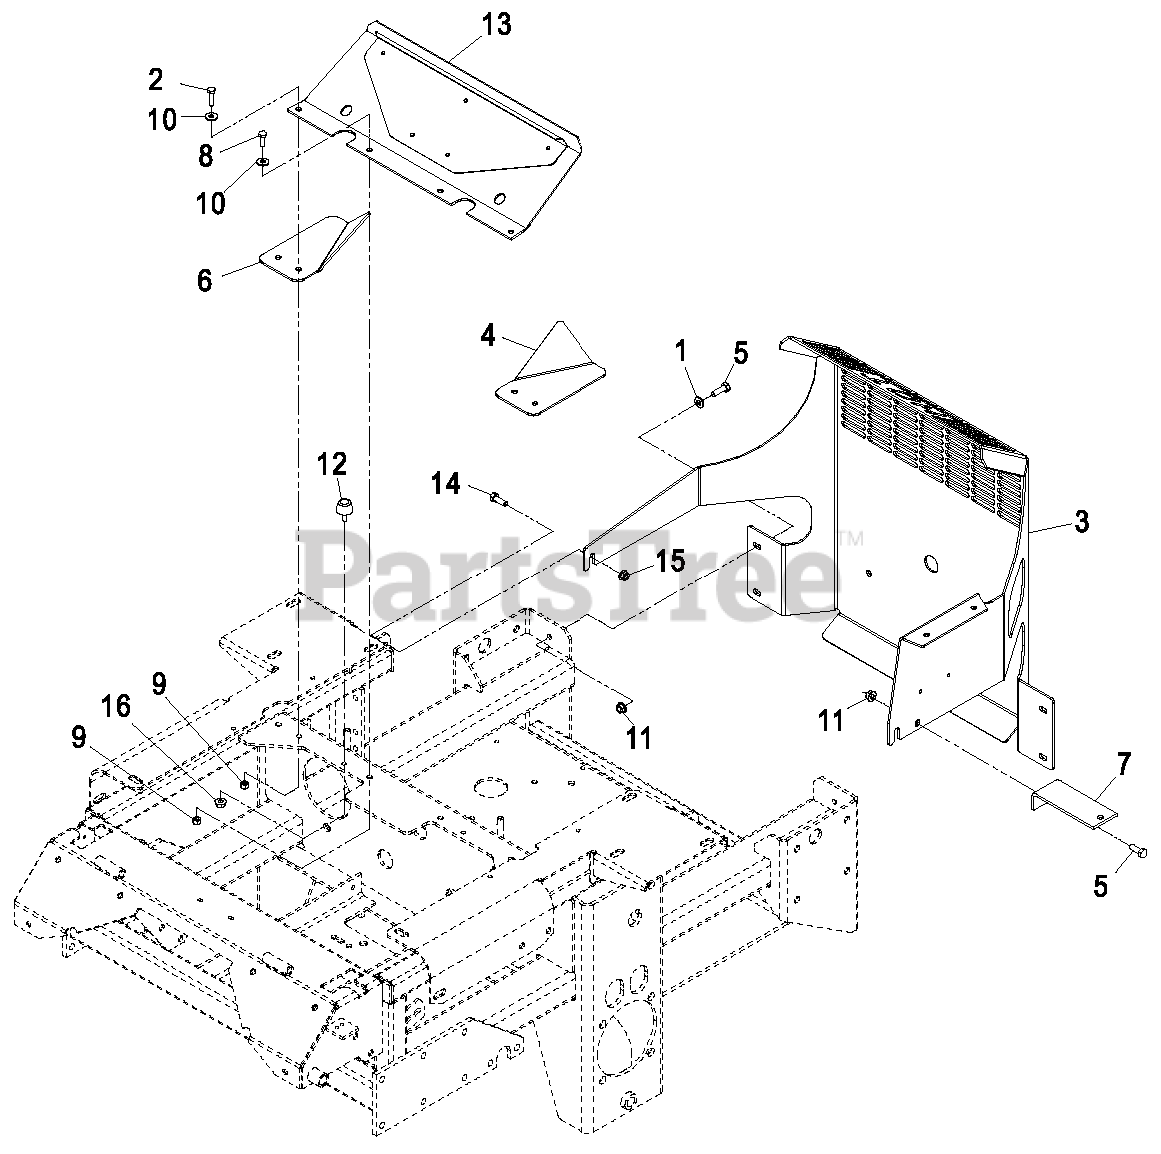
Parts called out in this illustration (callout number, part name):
1	WASHER-PLAIN
2	SCREW-HH
3	GUARD,REAR-LXS AC
4	SUPPORT-FRONT COVER, LH
5	SCREW-HH
6	SUPPORT-FRONT COVER, RH
7	BRACKET, HYDRAULIC TANK
8	SCREW-HH
9	NUT-LOCK, NI
10	WASHER-FLAT
12	BUMPER-RUBBER
13	KIT,FRONT ENGINE COVER W/
14	SCREW-HH
15	NUT-HHF, WHIZ
